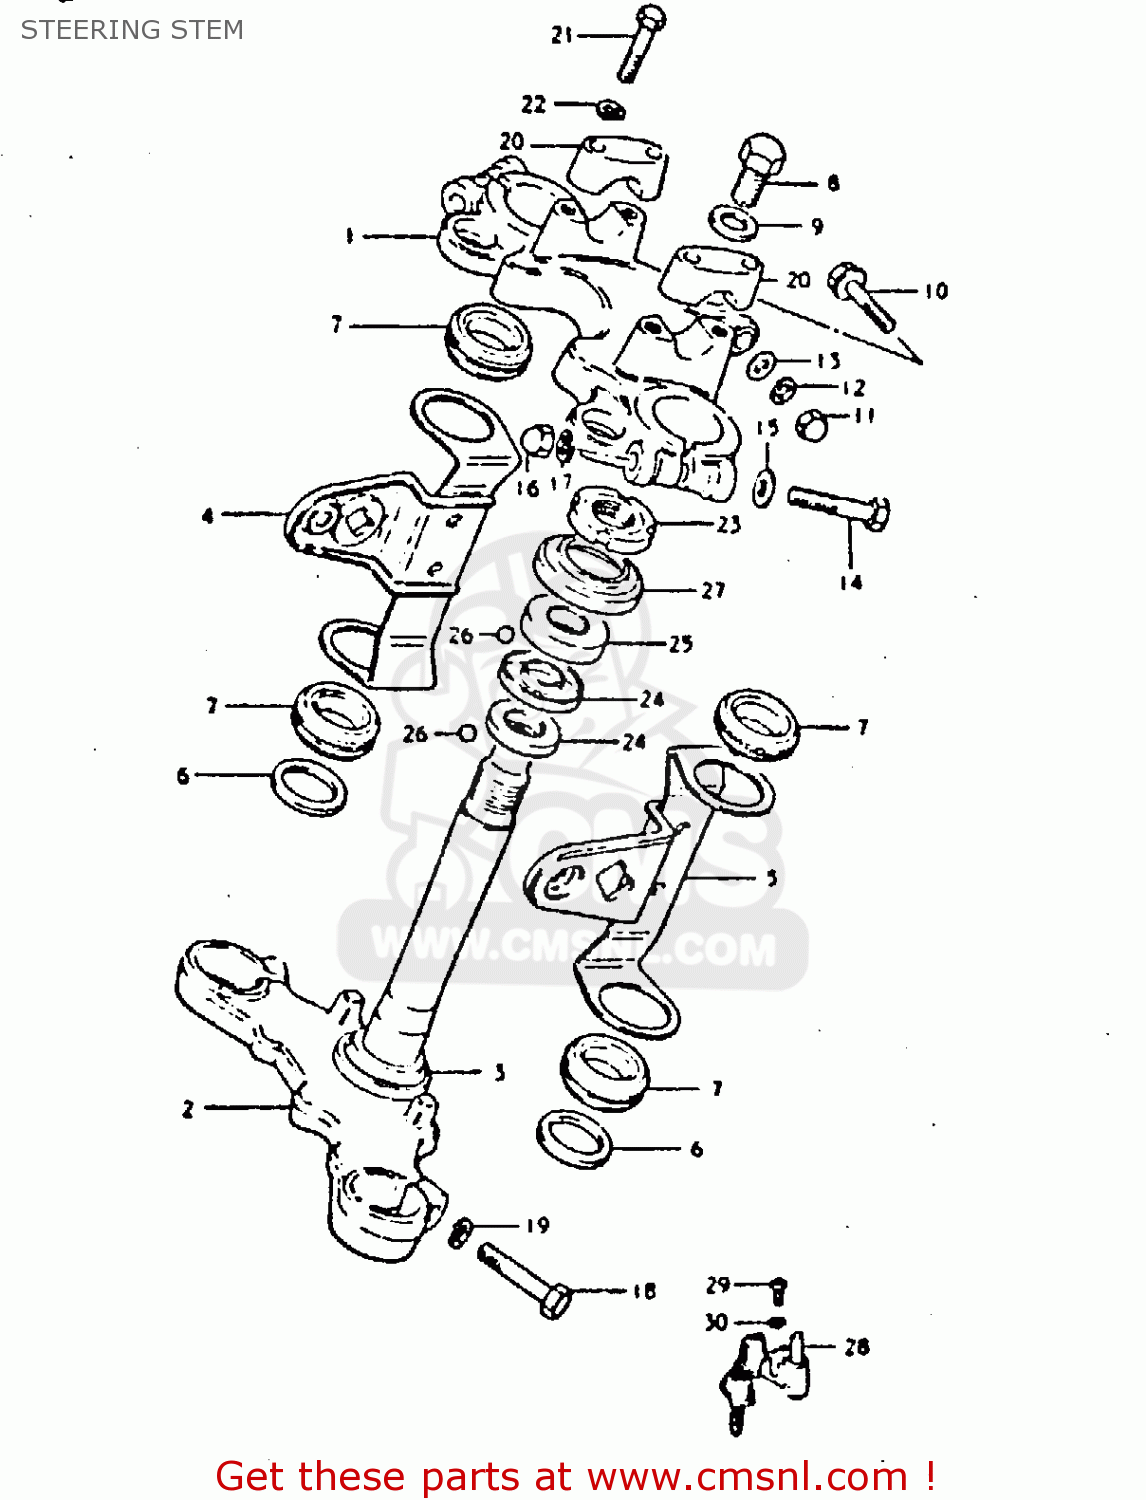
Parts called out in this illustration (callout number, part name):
1	HEAD,STEERING STEM
2	STEM,STEERING
3	RACE,STEERING OUTER LWR
4	BRACKET,HEADLAMP,RIGHT
5	BRACKET,HEADLAMP,LEFT
6	SEAT,HEADLAMP BRACKET LWR
7	CUSHION,HEADLAMP BRACKET
8	BOLT(12X20)
9	WASHER
10	BOLT
11	NUT
12	LOCK WASHER
13	WASHER
14	BOLT 10X55
15	WASHER
16	NUT
17	LOCK WASHER
18	BOLT 10X40
19	LOCK WASHER
20	HOLDER,HANDLE UPR
21	BOLT
22	LOCK WASHER
23	NUT,STEERING STEM(25X44X10)
24	LACE,STEERING INNER LWR
25	LACE,STEERING OUTER UPR
26	BALL
27	DUST SEAL,STEERING UPR
28	LOCK ASSEMBLY,STEERING
29	SCREW
30	LOCK WASHER
